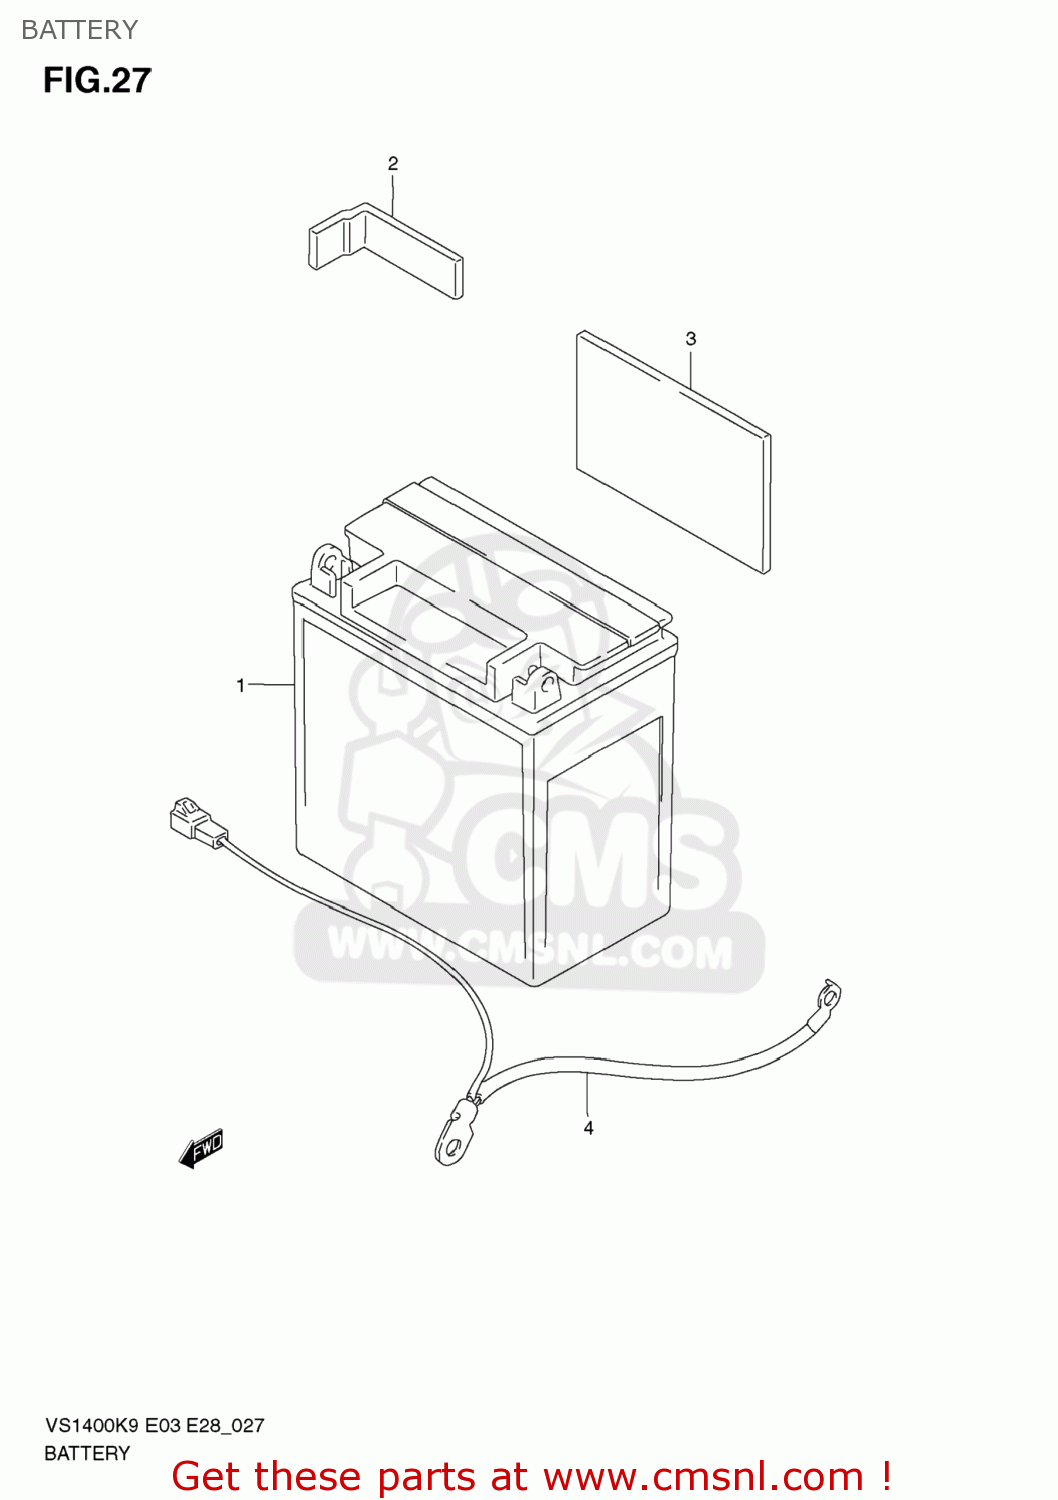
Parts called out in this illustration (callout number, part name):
1	BATTERY ASSEMBLY 12V14AH,F
2	PROTECTOR(20X90)X2
3	PROTECTOR(170X95X3.0)
4	WIRE,BATTERY MINUS LEAD
